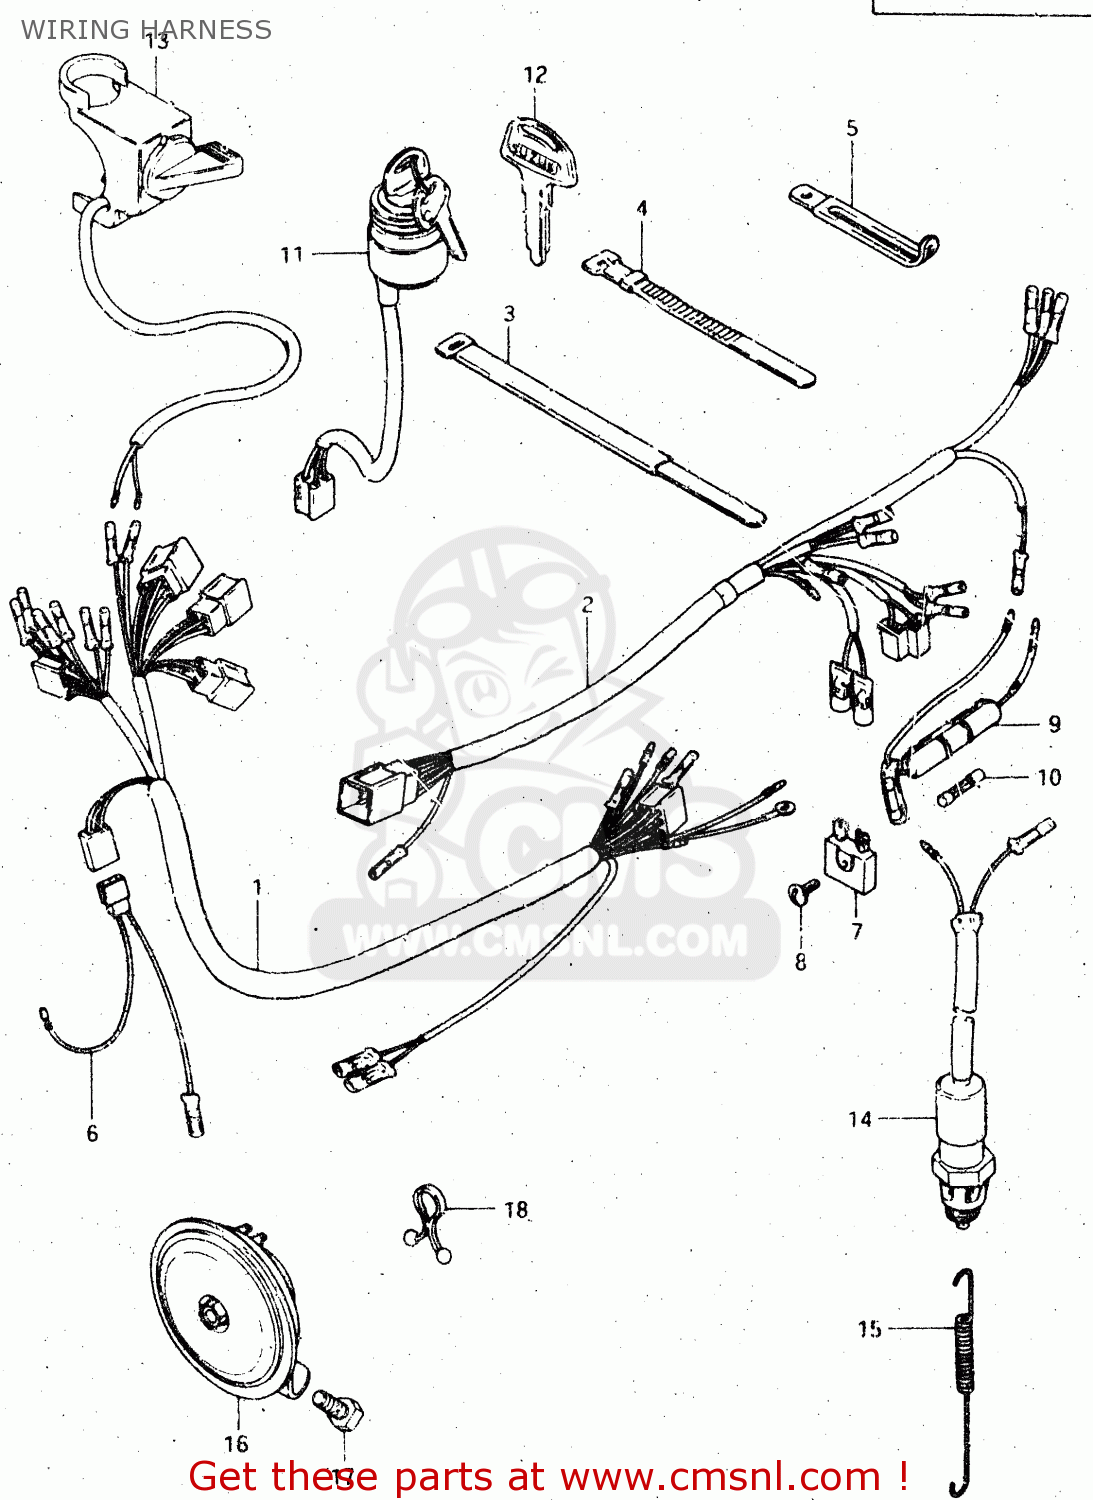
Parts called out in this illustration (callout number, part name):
1	WIRING HARNESS NO.1
2	WIRING HANRESS NO.2
3	CLAMP
4	CLAMP(L:120)
5	CLAMP
6	WIRE
7	RECTIFIER ASSEMBLY
8	SCREW(5X18)
9	CASE ASSY,FUSE
10	FUSE (15A)
11	SWITCH ASSY, IGNITION
12	KEY,BLANK
13	SWITCH ASSEMBLY
14	SWITCH ASSY,STOP LAMP
15	SPRING
16	HORN ASSY
17	BOLT
18	CLIP
